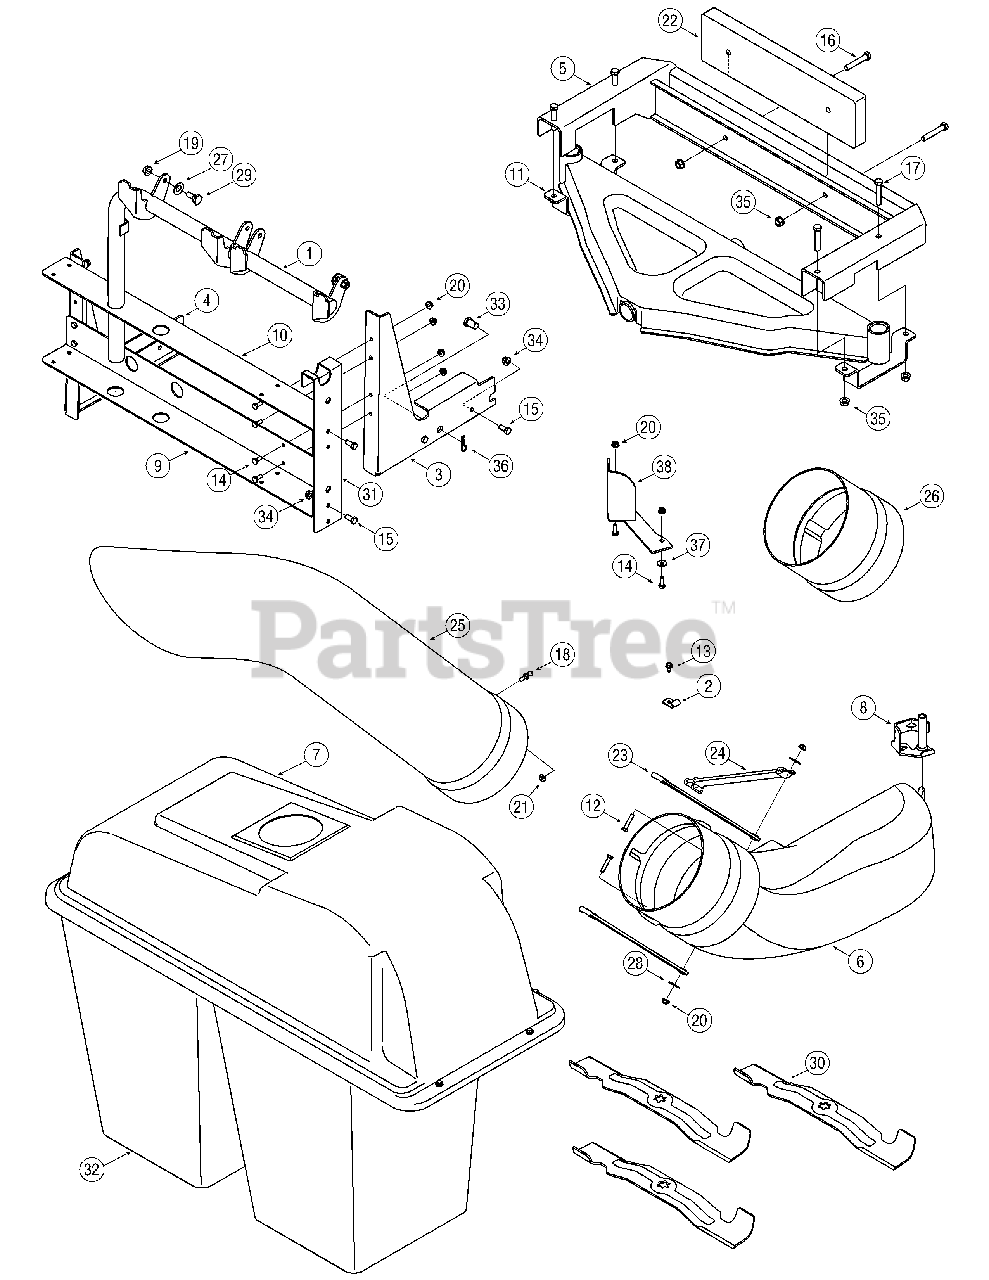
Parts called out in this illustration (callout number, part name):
2	Retainer Hook Bracket
6	Chute Elbow
7	Grasscatcher Cover Assembly
12	Hex Bolt 1/4-20 x 1.25
13	TT Screw 1/4-20 x 0.5
14	Hex Bolt 1/4-20 x 0.75
15	Hex Bolt 5/16-18 x 1.00
16	Hex Bolt 3/8-16 x 2.25
17	Hex Bolt 3/8-16 x 2.0
18	Grasscatcher Pin
19	Flange Lock Nut 3/8-16
20	Flange Lock Nut 1/4-20
21	Flange Lock Nut 1/4-20
22	Weight Bar
23	Chute Strap
24	Chute Strap
25	Chute Tube
26	Chute Extension
27	Bell Washer
28	Flat Washer
29	Shoulder Screw 3/8-16
32	Grass Bag Assembly
32	Screw, #10-24 x .5
32	Hex Sems Nut, 10-24
32	Bag
32	Self Tapping Screw, 5/16-18 x .625
33	Clevis Pin
34	Flange Lock Nut 5/16-18
35	Flange Lock Nut 3/8-16
36	Cotter Pin
37	Bell Washer
